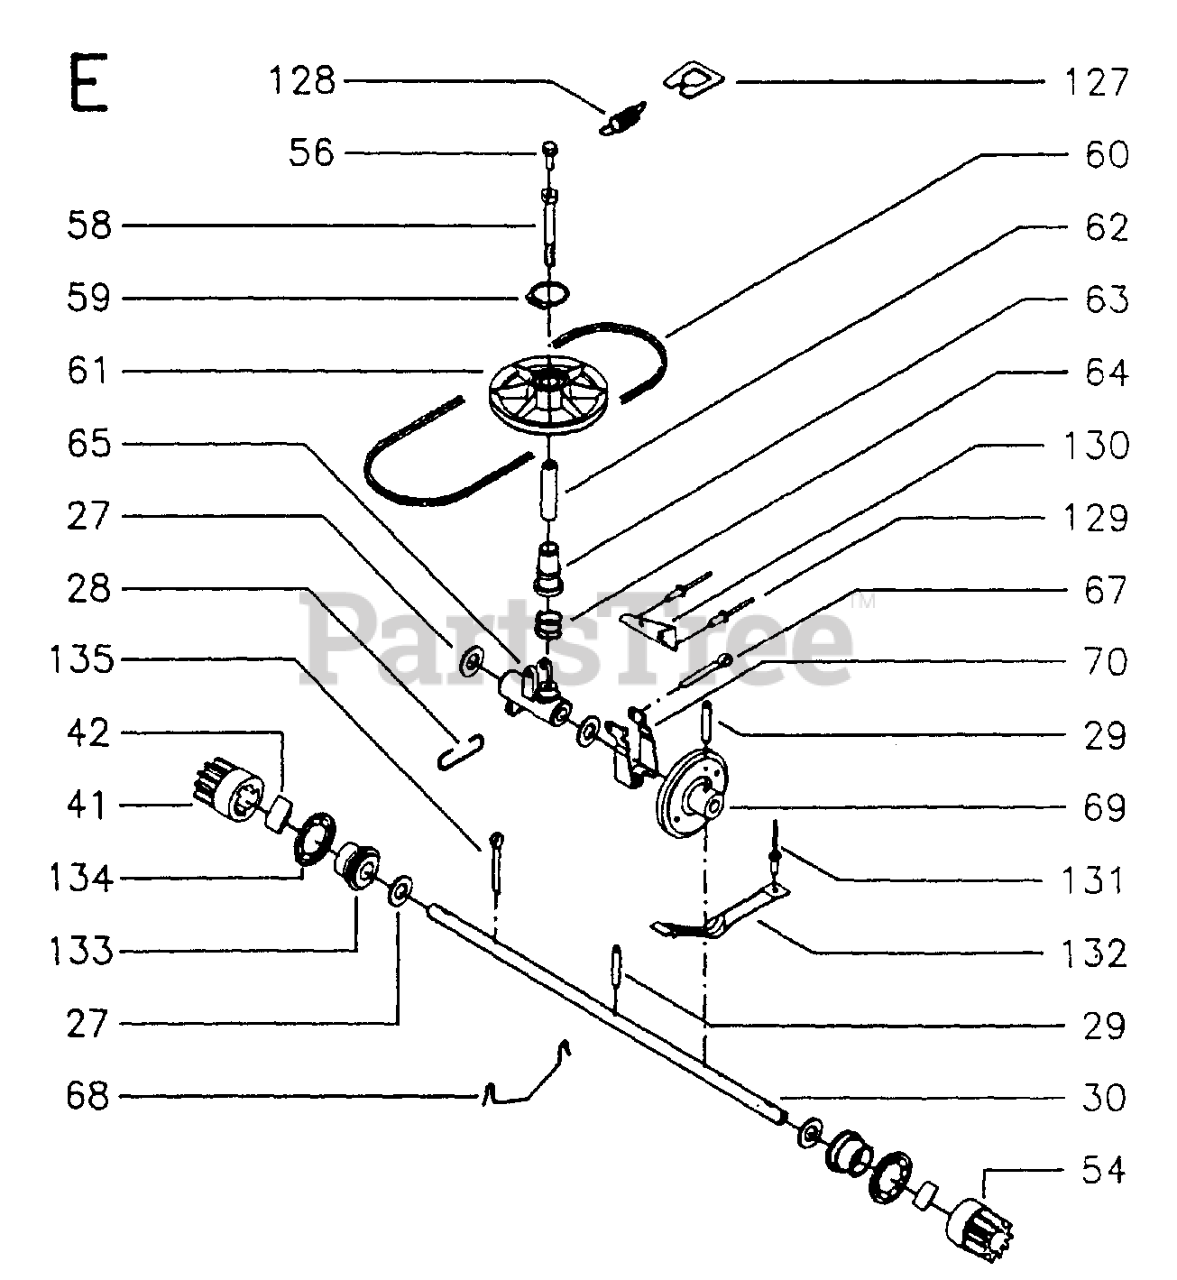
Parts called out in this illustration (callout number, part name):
27	WASHER
28	CLIPS
41	PINION, RIGHT
42	CARRIER
54	PINION, LEFT
56	SCREW TAPTITE
61	PULLEY W/BRG
63	SLEEVE
65	HOLDER
68	HOLDER SPACER
69	WHEEL ASSY FRICTION
70	RAM
127	SPRING FASTENING
131	REPL BY 516 92 38-00
134	LOCK WASHER
